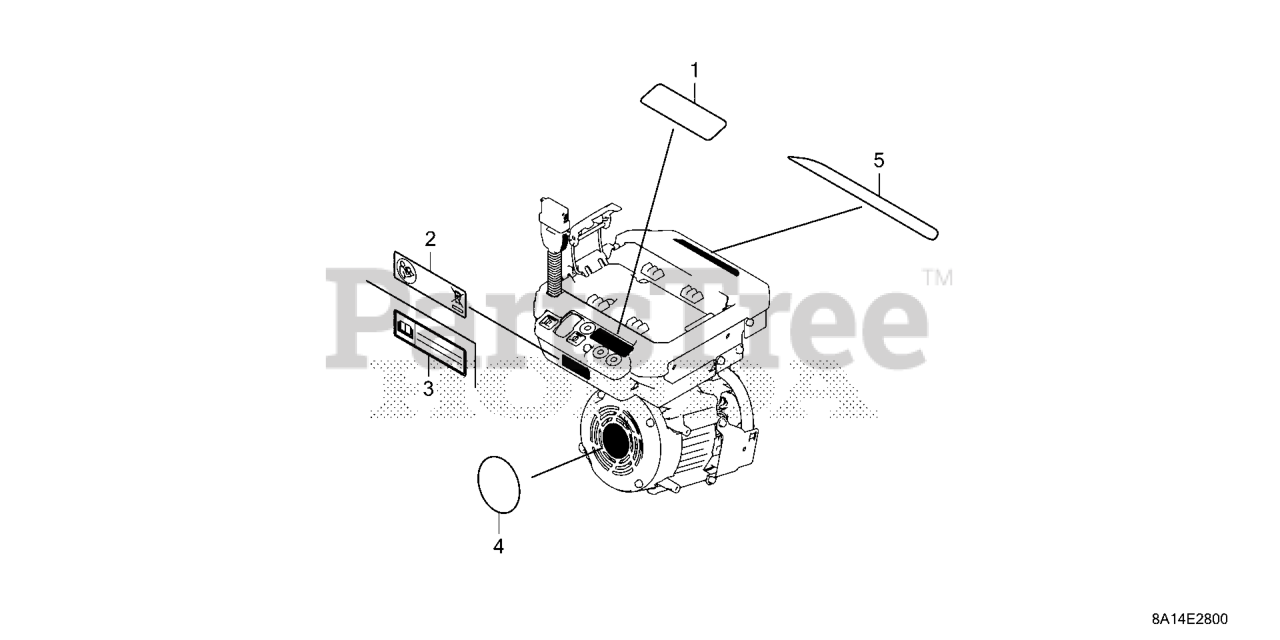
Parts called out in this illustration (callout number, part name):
1	MARK, LED INDICATION
4	MARK, EMBLEM
5	MARK, ELECTRIC POWER
